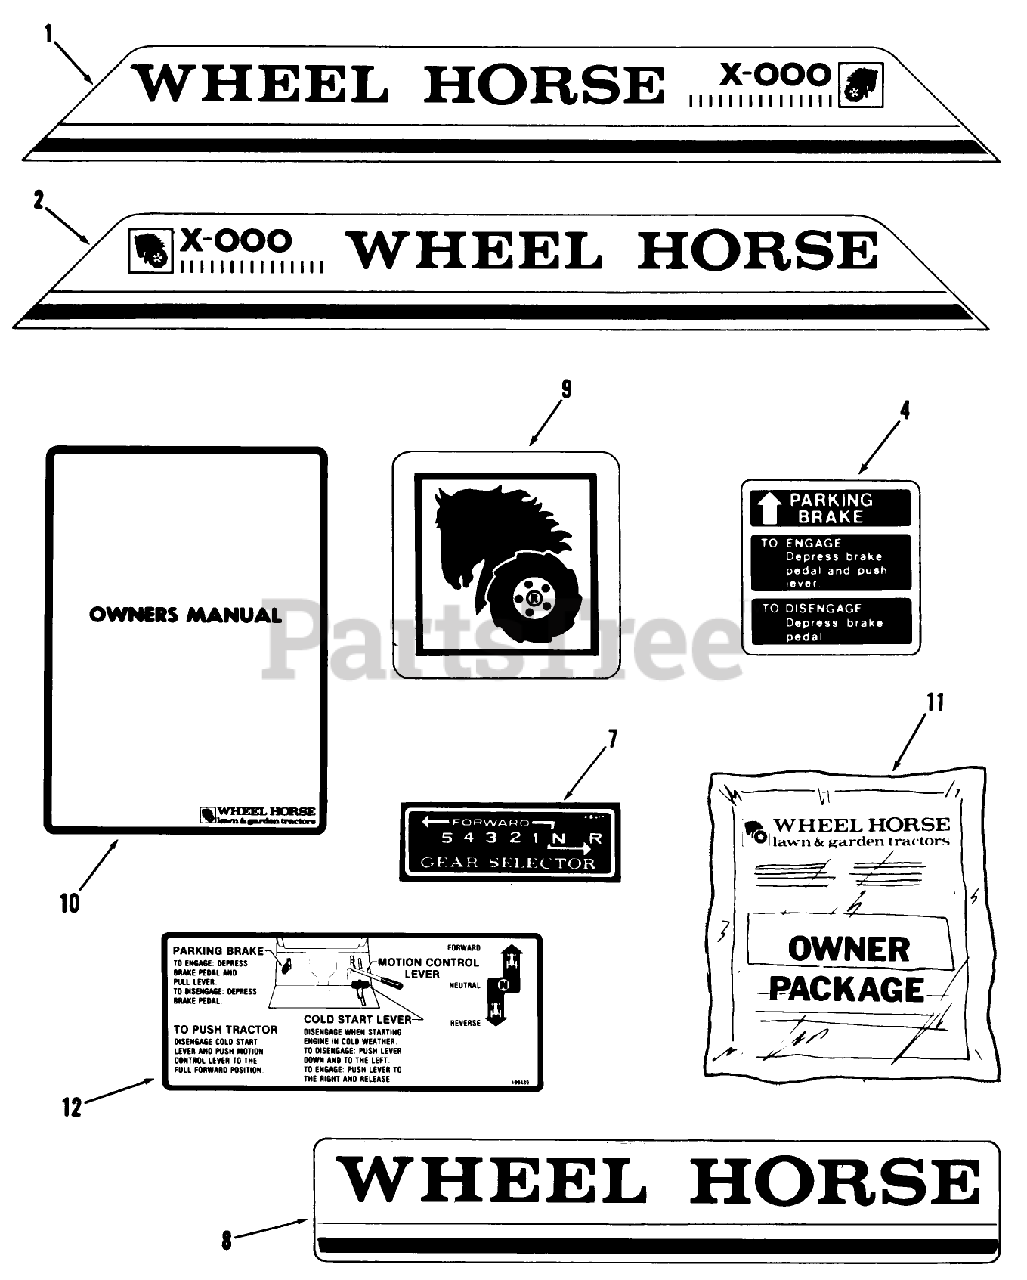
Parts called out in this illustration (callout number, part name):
8	DECAL-REAR
9	DECAL-LOGO
10	Owner-s Manual
11	New Tractor Loose Parts Package B-115 Automatic Only
11	New Tractor Loose Parts Package B-165 Automatic Only
